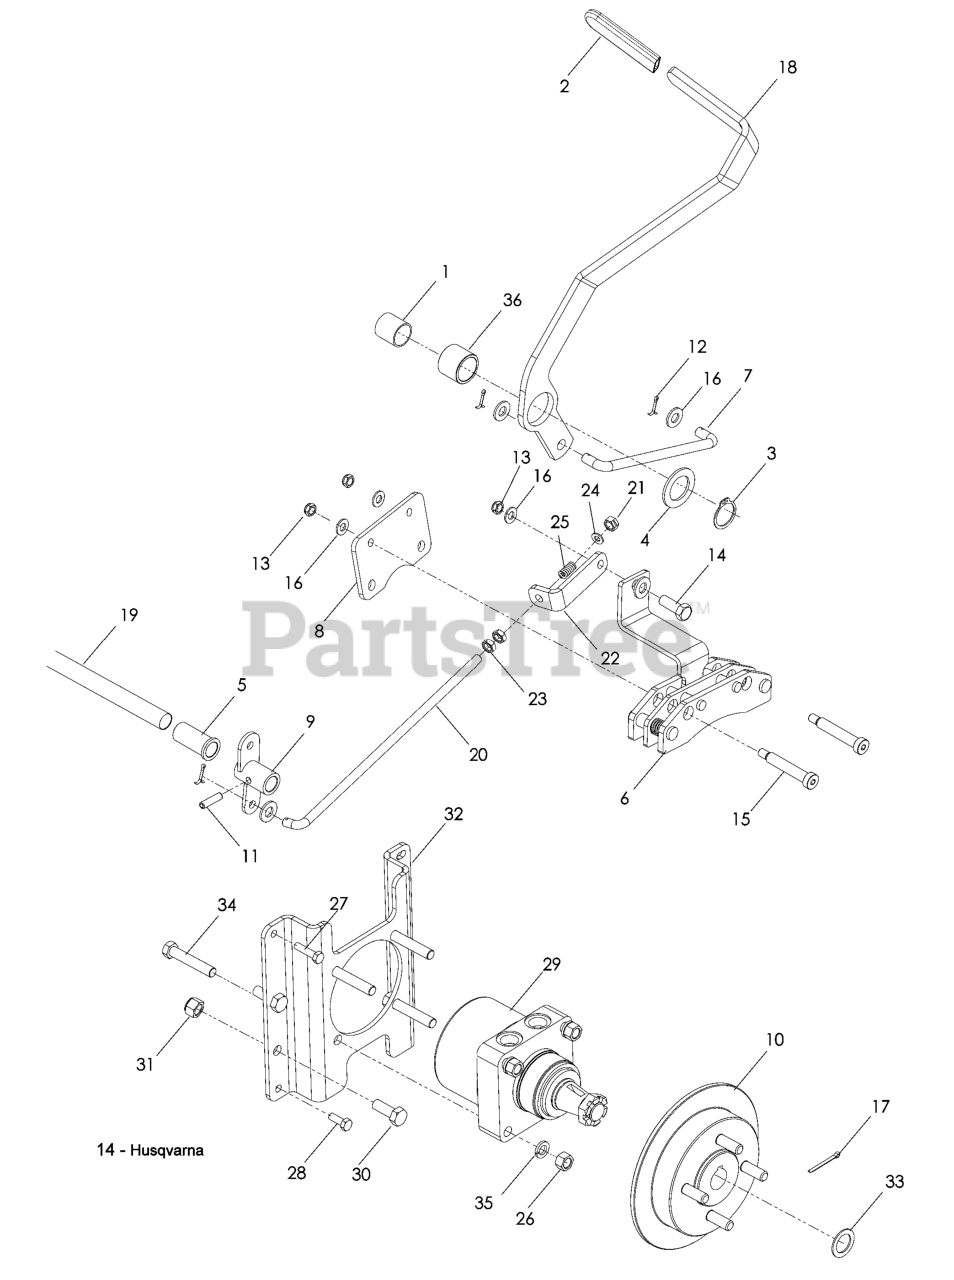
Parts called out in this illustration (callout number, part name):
2	GRIP, PARK BRAKE
3	RETAINING RING, 7/8"
4	BSHG .875 X 1.375 X .074 ZD
5	BUSHING, POLYMER 3/4X2
7	LINKAGE, BRAKE
8	PLATE, BRAKE
9	BELLCRANK, BRAKE
11	5/16 DIA ROLL PIN
12	COTTER PIN 3/32 X 3/4
13	NUT HEX 3/8-16 NYLON, THIN
14	HCS 3/8-16X1.GRD.5.ZD
15	SB 3/8-16 X 2-1-1/2 SKT HDD ZD
16	WASHER 3/8 SAE FLAT
17	PIN COTTER 4MM X 45MM
18	BRAKE LEVER WLDMT
20	LINKAGE, REAR BRAKE
21	NUT 3/8F CENTERLOCK
22	BRACKET, L
23	NUT 3/8-24 JAM
24	WASHER 3/8 SAE FLAT
26	NUT HEX 1/2
27	HCS 3/8C X 1 1/4 GR5
28	HCS 3/8C X 2 1/4
29	TL15 WHEEL MOTOR
30	HCS 1/2C X 1 1/4 SERRATED HEAD
31	NUT 1/2-13 HEX NYLOC ZD
32	MOUNT, MOTOR, WHEEL - BLK
33	MACHINE BUSHING
34	HCS 1/2C X 2 3/4
35	WASHER 1/2" SPLIT LOCK
36	BRAKE LEVER TUBE
